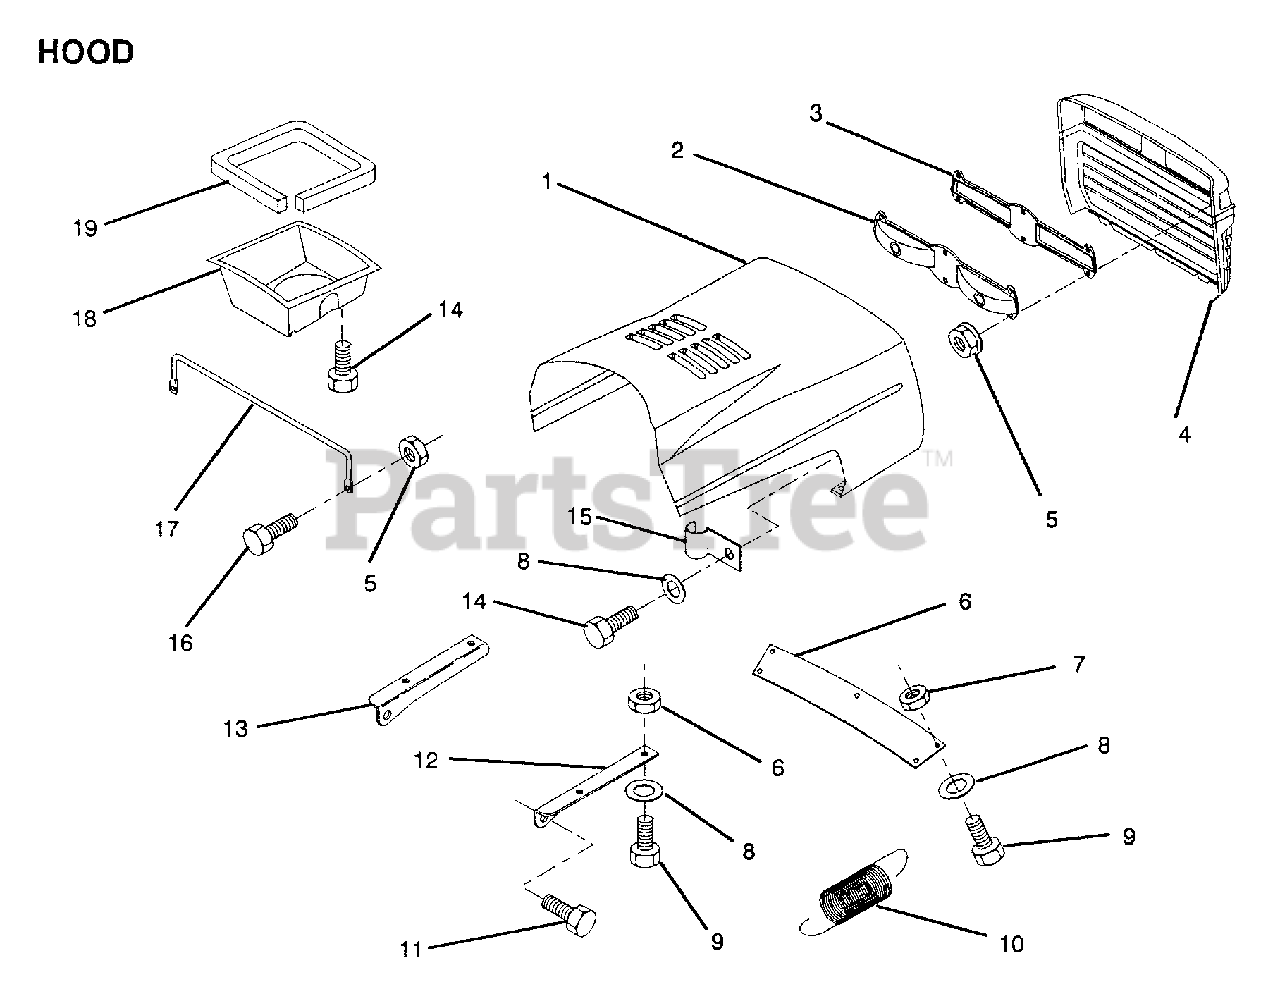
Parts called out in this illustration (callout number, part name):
5	NUT
6	"STRAP,GRILL T"
7	NUT
8	WASHER
9	BOLT
10	EXT SPRING
12	BRKT HOOD RH
13	BRKT HOOD LH
15	CLIP T
17	"BRACE,HOOD"
18	"DUCT,AIR"
19	FOAM STRIP LT
